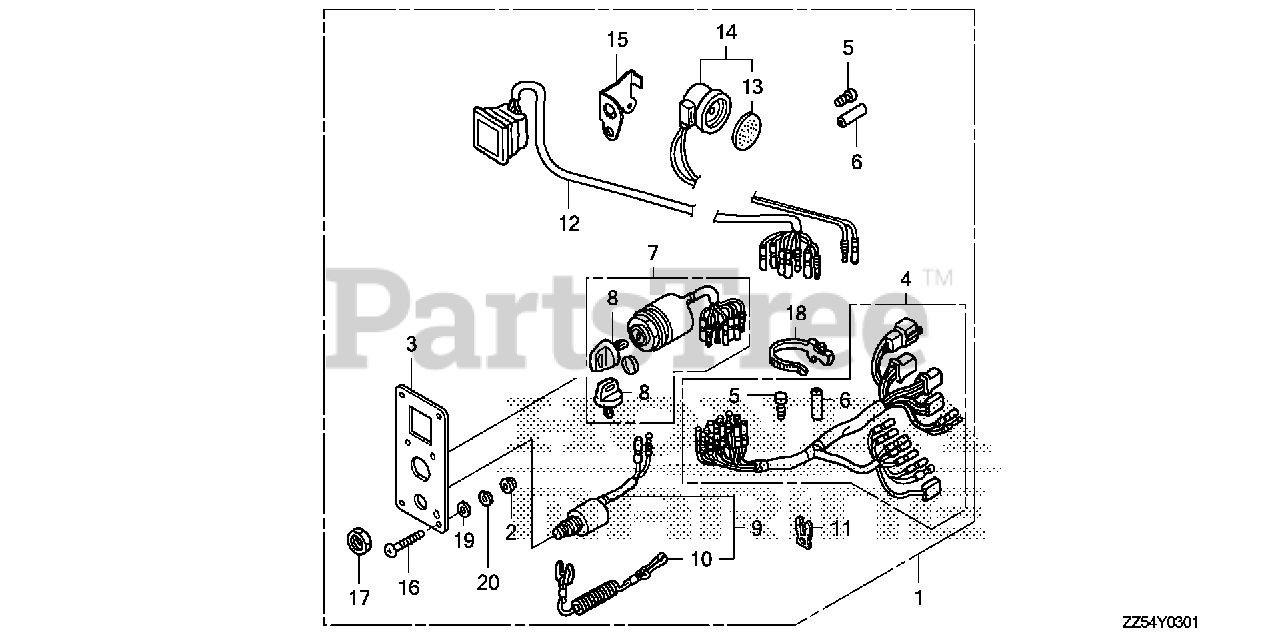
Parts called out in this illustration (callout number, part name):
1	PANEL KIT, SWITCH (4-LED)
2	NUT, FLANGE (5MM)
3	PANEL, CONTROL
4	HARNESS ASSY., SWITCH PANEL
5	PLUG, CONNECTOR (INNER)
6	PLUG, CONNECTOR (OUTER)
7	SWITCH ASSY., COMBINATION
8	KEY ASSY., COMBINATION SWITCH (35100-ZV5-003 ONLY)
9	SWITCH ASSY., EMERGENCY STOP
10	WIRE, EMERGENCY
11	CLIP, EMERGENCY LOCK
12	LAMP ASSY., INDICATION (4-LED)
13	PLATE, TURN SIGNAL BUZZER
14	BUZZER, WARNING
15	BRACKET, BUZZER
16	SCREW, PAN (5X40)
17	NUT, HEX. (16MM)
18	BAND, WIRE HARNESS (150MM) (NATURAL)
19	WASHER, PLAIN (5MM)
20	WASHER, SPRING (5MM)
